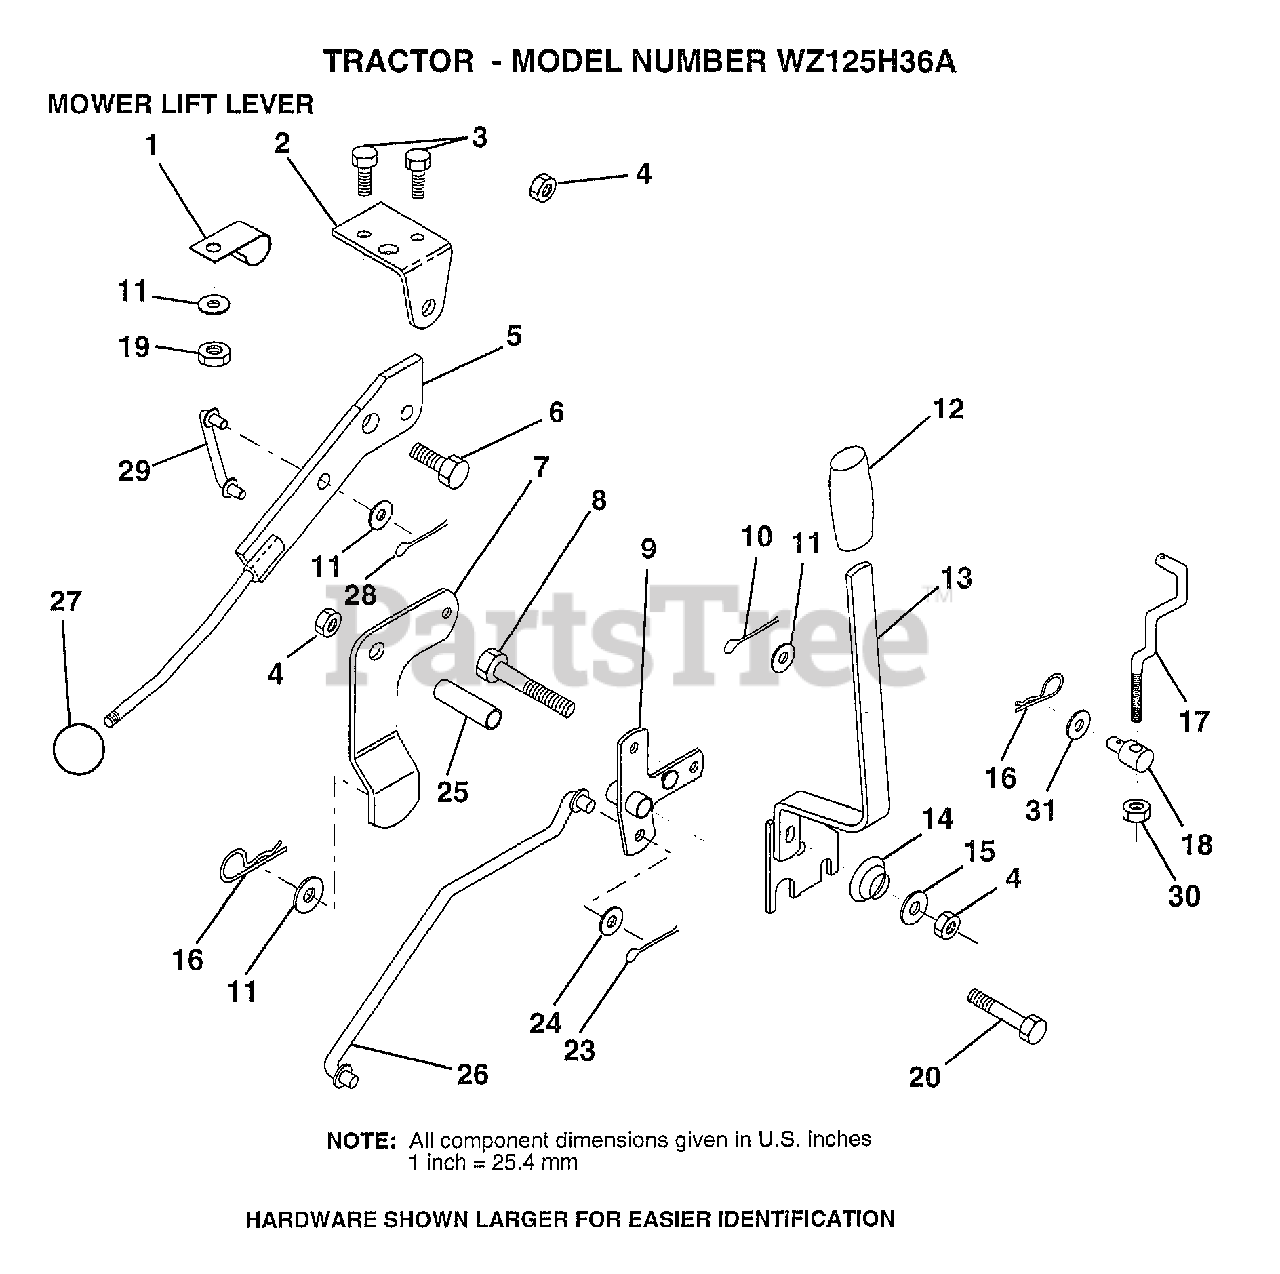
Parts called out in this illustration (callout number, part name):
1	"CLIP,INSULATOR"
2	BRKT CLUTCH
3	BOLT HXHD FIN
5	LEVER.ASM.CLUTCH
6	"BOLT, SHOULDER LT"
7	MWR CLUTCH ARM AS
8	BOLT
9	"BELLCRANK,LIFT"
10	COTTER PIN
11	WASHER
13	HANDLE.ASM.LIFT
14	SPRING COMPRESSIO
15	WASHER T
17	"LINK,LIFT FRT"
18	TRUNION ADJ
20	BOLT
23	PIN COTTER 1/8
25	TUBE SPACER
26	ROD LIFT MOWER
27	KNOB T(3/8 HOLE)
29	CLUTCH LINK
30	NUT
31	WASHER
